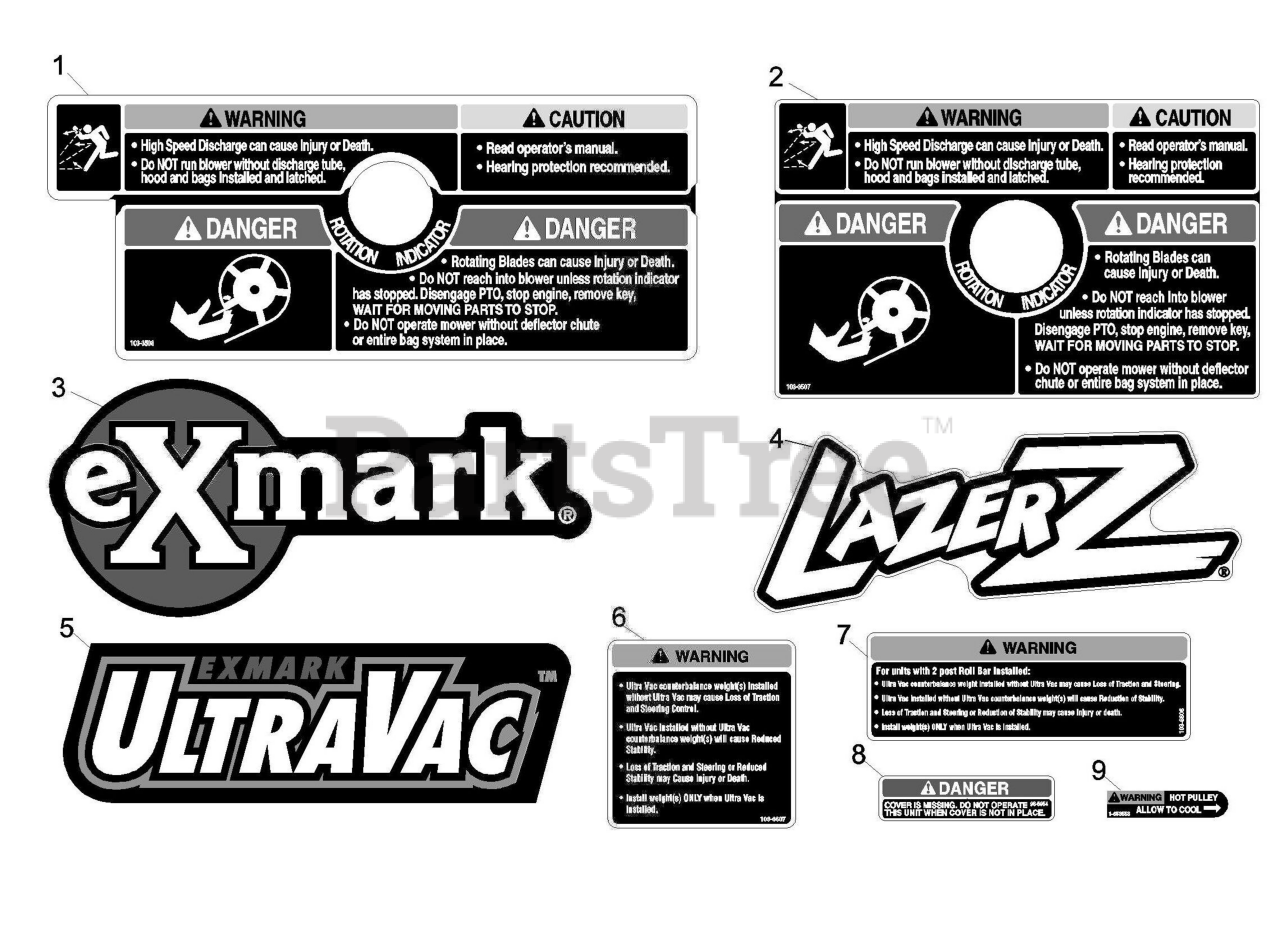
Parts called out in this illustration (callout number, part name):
1	DECAL-WARNING
3	DECAL, EXMARK LOGO
4	DECAL,LAZER MODEL
5	DECAL, ULTRAVAC
6	DECAL,WEIGHT
7	DECAL,WEIGHT
8	DECAL-COVER, MISSING
9	DECAL-WARNING
